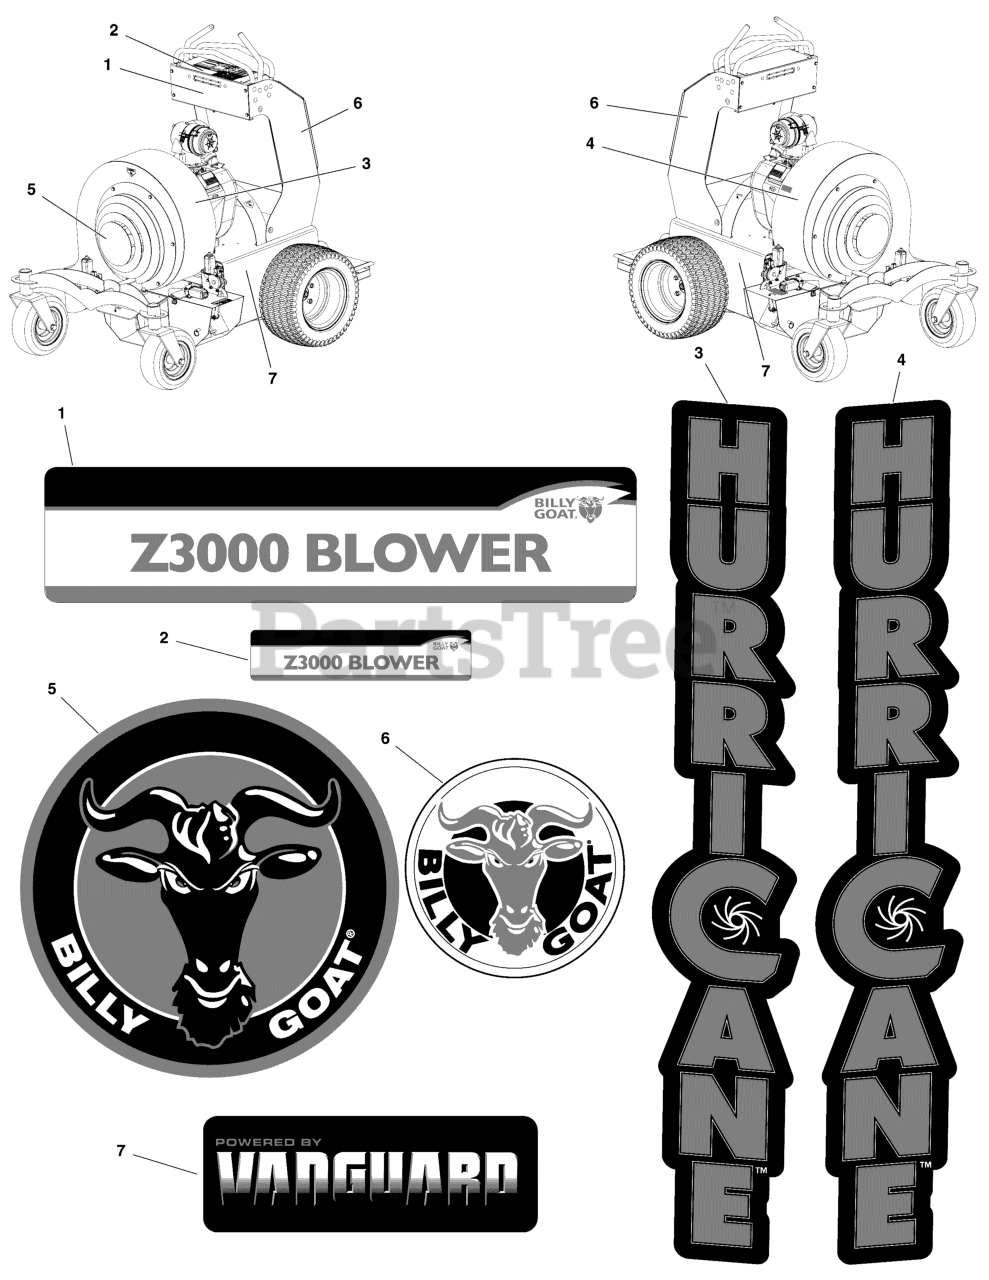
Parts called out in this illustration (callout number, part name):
1	DECAL, Z3000 BADGE
2	DECAL, Z3000 TOP PANEL
3	DECAL, Z3000 HURRICANE_VERT, BG,LH
4	DECAL, Z3000 HURRICANE_VERT, RH
5	DECAL, Z3000 FRONT LOGO
6	LABEL, PRODUCT DECAL LG CIRCLE
7	DECAL, BRAND
